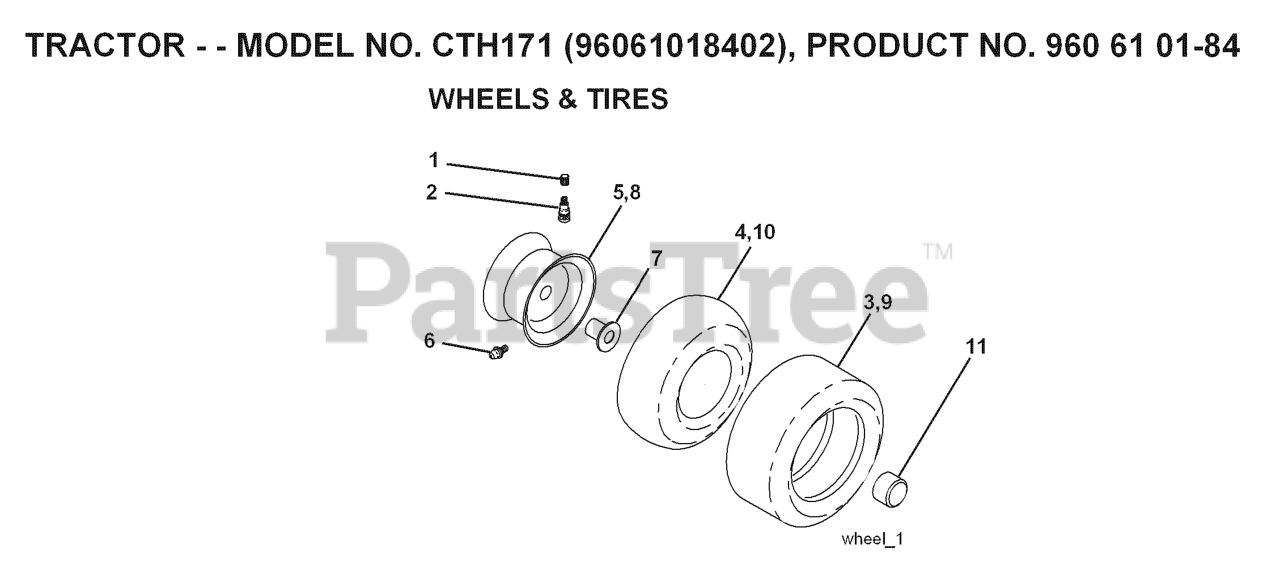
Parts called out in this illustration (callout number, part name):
2	VALVE STEM LT
3	TIRE HEAVY DUTY
4	TUBE.5.3/4.5/6
5	RIM ASM 6" FRONT SILVER
6	FITTING LT
7	BEARING T
8	RIM ASM 8" REAR SILVER
9	TIRE.TS.20X10-8
10	TUBE
11	CAP, AXLE BLK
